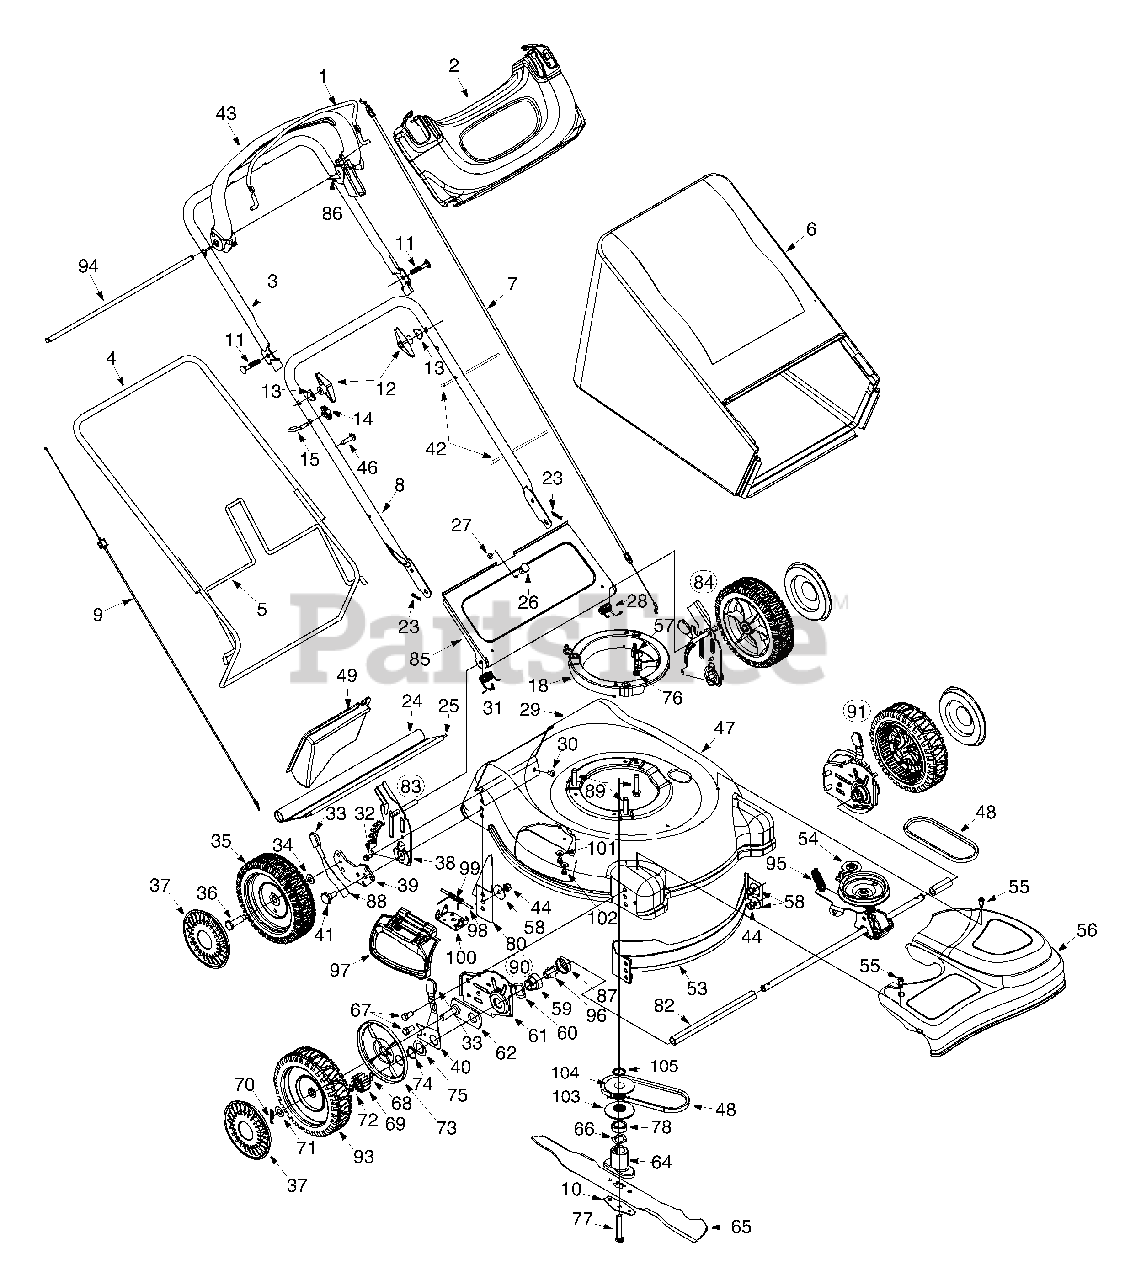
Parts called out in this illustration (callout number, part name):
1	Bail Handle
2	Handle Panel
7	Control Cable
9	Drive Cable
10	Blade Bell Support
11	Carriage Bolt
12	Handle Knob
13	Saddle Washer
15	Rope Guide
18	Engine Spacer Assembly
23	Hairpin Clip
24	Rear Trail Shield
25	Wire: Trail Shield
27	Scr. Tr. Mach. #10-24 x 0.380"
28	Torsion Spring LH
30	Scr. AB 1/4-14 x 0.625"
31	Torsion Spring RH
32	Hex Scr. w/ Wash. 1/4-14 x 0.62"
33	Knob
34	Bell Washer .375 x .870
35	Rear Wheel: Disk Bar Gray
36	Shoulder Screw
37	Hubcap: Radial Spoke Grey
39	Pivot Bar LH
40	Front Lever RH
41	Shoulder Screw
42	Cable Tie
43	Drive Handle
44	Hex Nut 3/8-16
46	TT-Scr. 5/16-18
49	Mulch Plug
55	Shld. Screw
56	Front Drive Cover: Black
57	Belt Keeper Pin
58	Bell Washer
59	Bearing Support
60	Wave Washer
62	Pivot Plate Assembly
64	Blade Adapter
65	Mulching Blade w/ Star: 21"
66	Wave Washer
67	Hex Screw 3/8-16
68	Dowel Pin
69	Gear 14T RH
70	Hairpin Clip
71	Flat Washer
72	Snap Ring
73	Wheel Dust Cap
74	Snap Ring
75	Washer DD 1.5" O.D.
76	Hex Nut 1/4-20
78	Sleeve Spacer, .88 x 1.19 O.D.
82	Slev. Spacer LH
83	Handle Bracket Assembly RH Compl.
84	Handle Bracket Assembly LH Compl.
87	Bearing Retainer
88	Spring Lever
90	Height Adj. Assembly RH Compl.
91	Height Adj. Assembly LH Compl.
93	Wheel, 8x2 x 1.75
94	Control Rod
95	Extension Spring
96	Bearing Sleeve .50 I.D.
97	Mulch Plug
98	Hinge Pin
99	Torsion Spring
101	Bell Wash. 0.265" x 0.75"
102	TT-Screw 1/4-20 x .05"
103	Half Pulley
104	Half Pulley
105	Sleve Spacer .88 I.D. x 1.130 O.D.
